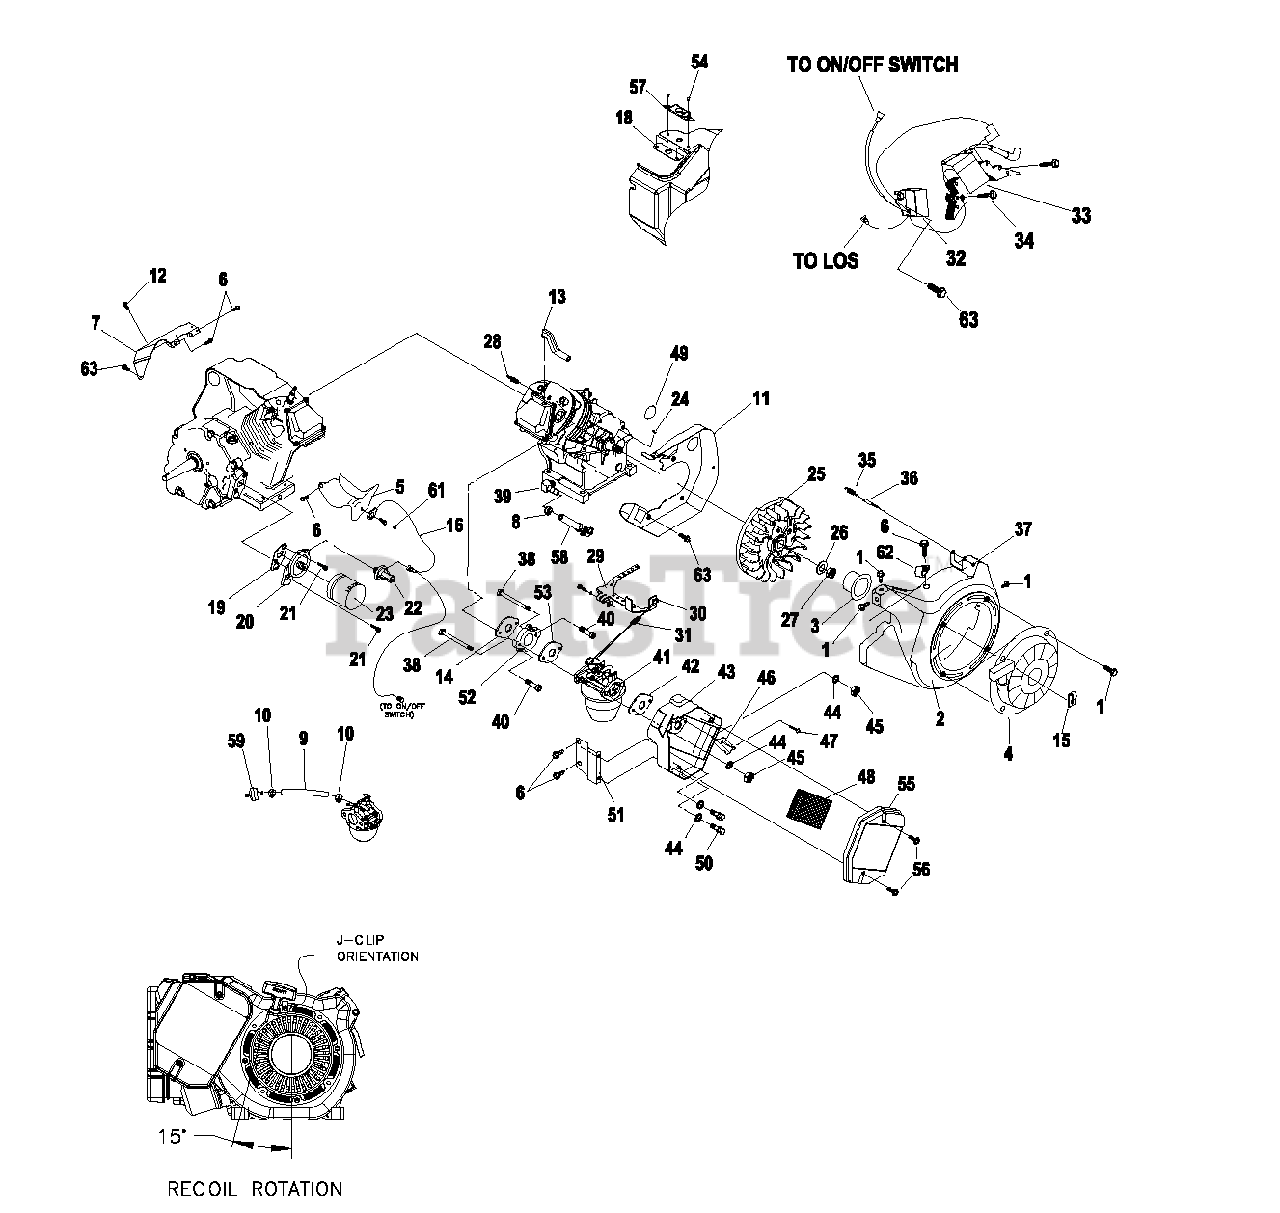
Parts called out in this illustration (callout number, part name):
1	SCREW HHTT M6-1.0 X 8
2	ASSEMBLY, BLOWER HOUSING
3	PULLEY STARTER LARGE FRAME
4	RECOIL STARTER LARGE FRAME
5	WRAPPER BOTTOM
6	SCREW HHTT M6-1.0 X 10
7	WRAPPER TOP
8	CLAMP HOSE OETIKER STEPLESS 18.5
9	FUEL HOSE 250MM LONG
10	CLAMP HOSE BAND .41
11	BACKPLATE
12	SCREW HHTT 5/16-18 X 1/2"
13	HOSE BREATHER GH410
14	GASKET INTAKE ADAPTOR
15	CLIP-J VINYL COATED
16	WIRE HARNESS
18	BACK PLATE SUPPORT
19	GASKET OIL FILTER ADAPTOR
20	ADAPTOR OIL FILTER
21	SCREW SHC M8-1.25 X 30
22	SWITCH OIL PRESSURE 5PSI
23	FILTER OIL BLACK 75MM LONG
24	KEY WOODRUFF 4 X 19D
25	FLYWHEEL LARGE FRAME 27 DEG
26	WASHER BEL V-20 X 2.2
27	NUT HEX M20-1.5
28	SPARKPLUG, CHAMPION RC14YC 0.030"
29	ASSEMBLY GOVERNOR LEVER
30	ROD GOVERNOR CONTROL
31	SPRING ANTI-LASH
32	OIL PRESSURE SHUTDOWN MODULE
33	ASSEMBLY IGNITION ADV NO DIODE
34	SCREW HHFC M6-1.0 X 25
35	SPRING GOVERNOR
36	BOLT GOVERNOR ADJUSTMENT M5
37	NUT HEX LOCK M5-0.8 NYLON INSERT
38	BOLT CARBURETOR MOUNTING
39	BARBED ELBOW 90 DEG 3/8" NPT X 3/8"
40	FLANGED HEAD SCREW SHC M6-1.0 X 20
41	CARBURETOR ASSEMBLY
42	GASKET AIR CLEANER
43	BASE AIRCLEANER 410 HI FLOW
44	WASHER FLAT M6
45	NUT HEX LOCK M6-1.0 W/LOCK WASHER
46	PLATE SPITBACK
47	SCREW PLASTITE #8 X .37 LONG
48	ELEMENT AIR FILTER
49	PLUG PLASTIC 1.875
50	SCREW HHC M6-1.0 X 16 W/LOCK WASHER
51	BRACKET AIR CLEANER
52	ADAPTOR "K"
53	GASKET CARBURETOR / MANIFOLD
54	RIVOT 1/8"
55	COVER AIR CLEANER
56	BOLT AIR CLEANER COVER
57	BRACKET CHOKE CABLE
58	ASSY OIL DRAIN 6"
59	FUEL FILTER
61	GROMMET
62	C-CLIP STL/VINLY .437 X .281
63	SCREW HHFC M6-1.0 X 12
